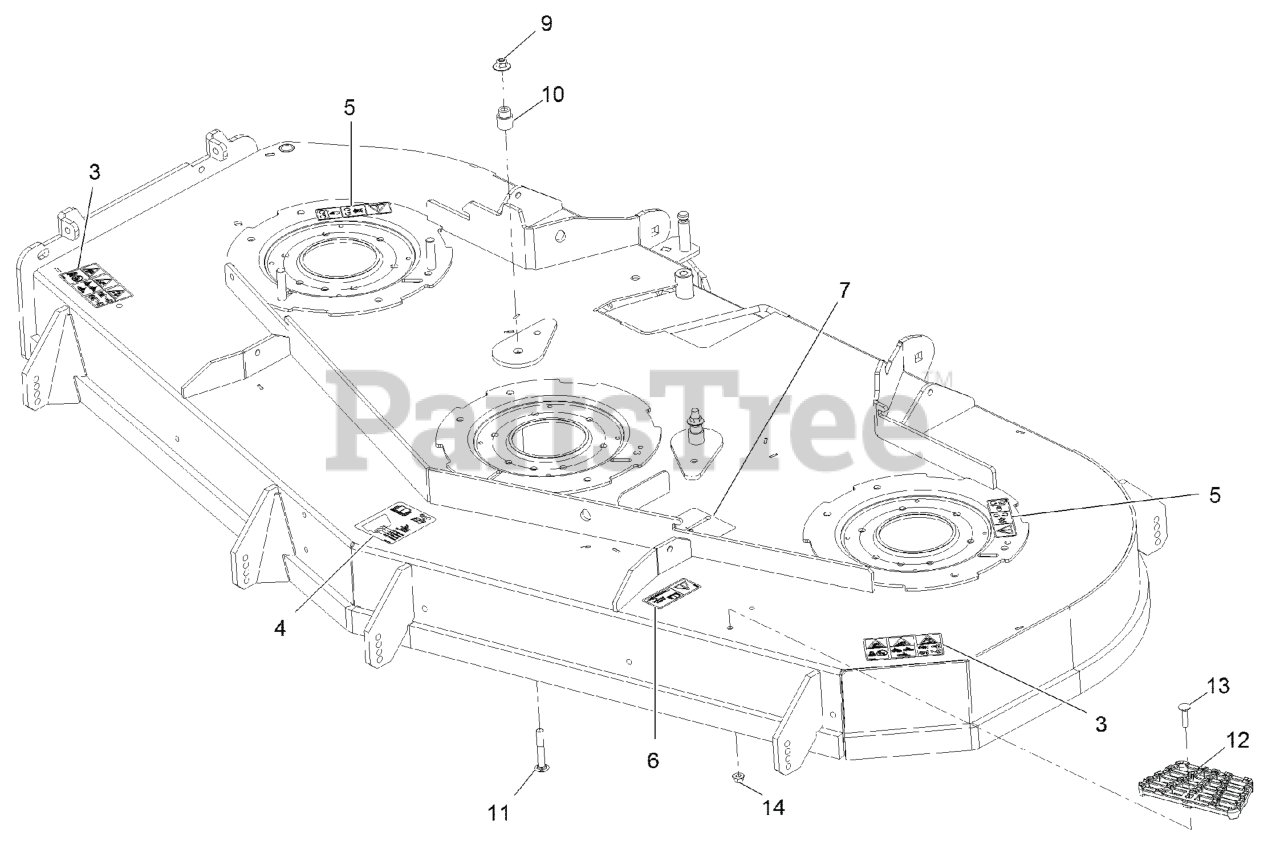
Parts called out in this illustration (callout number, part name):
3	DECAL-DANGER THROWN OBJECTS
4	DECAL-ROLLER, ANTI-SCALP
5	DECAL-COVER, MISSING
6	DECAL-TORQUE, BOLT
7	DECAL-BELT ROUTING
9	Nut-Nyloc 3/8-16 Flg
10	BUSHING-IDLER
11	SCREW-CARR
12	STEP-DECK
13	Bolt-Carriage 5/16-18 X 1 1/4
14	NUT-HF, NI
